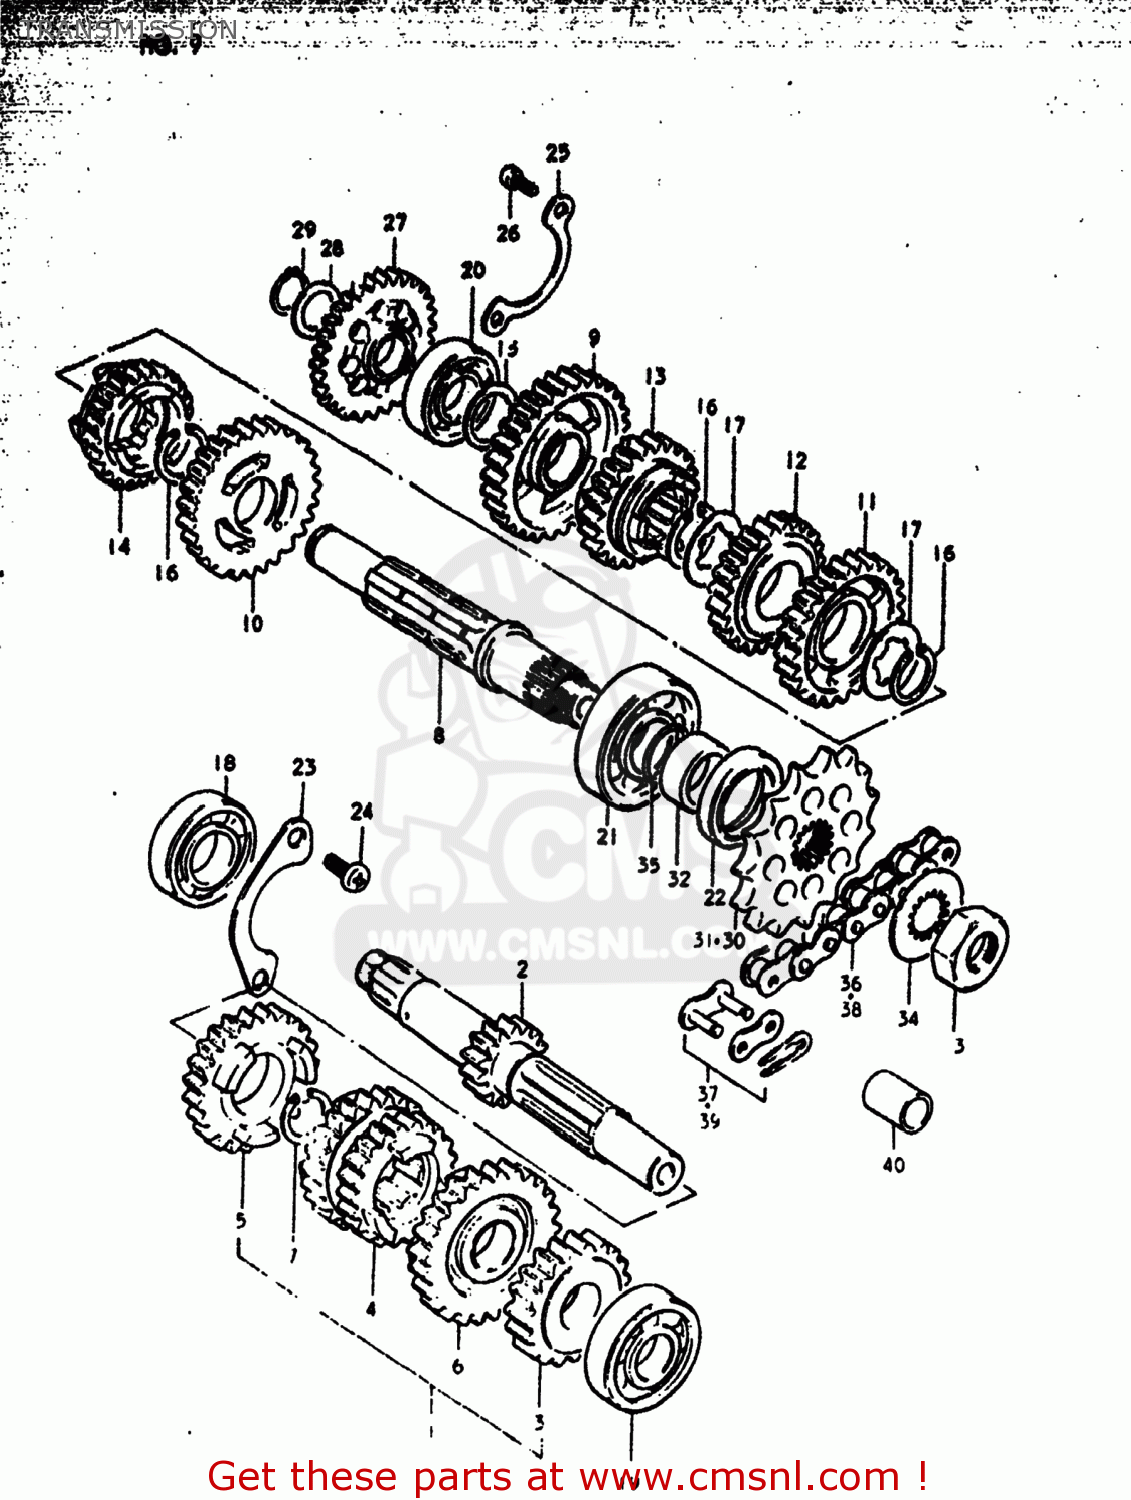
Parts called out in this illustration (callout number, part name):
1	SHAFT,COUNTER
2	SHAFT,COUNTER
3	GEAR,SECOND DRIVE
4	GEAR,THIRD DRIVE
5	GEAR,FIFTH DRIVE
6	GEAR,SIXTH DRIVE
7	CIRCLIP
8	SHAFT,DRIVE
9	GEAR,FIRST DRIVEN
10	GEAR,SECOND DRIVEN
11	GEAR,THIRD DRIVEN
12	GEAR,FOURTH DRIVEN
13	GEAR,FIFTH DRIVEN
14	GEAR,SIXTH DRIVEN
15	WASHER,THRUST
16	CIRCLIP
17	WASHER,LOCK
18	Bearing
19	BEARING
20	BEARING, RH
21	BEARING(20X47X14)
22	SEAL,OIL(25X40X7)
23	RETAINER,CNTR SHAFT BEARING
24	SCREW 6X12
25	PLATE,DRIVESHAFT BEARING
26	SCREW
27	GEAR,KICK STARTER IDLE
28	WASHER,THRUST
29	CIRCLIP,15MM
30	SPROCKET,ENGINE
31	SPROCKET,ENGINE
32	SPACER(20X25X12.5)
33	NUT
34	WASHER,LOCK
35	O RING(D:1,ID:19.5)
36	CHAIN,DRIVE #428TR-13
37	JOINT ASSEMBLY,CHAIN
38	CHAIN ASSEMBLY,DRIVE
39	JOINT ASSEMBLY,CHAIN
40	CUSHION
